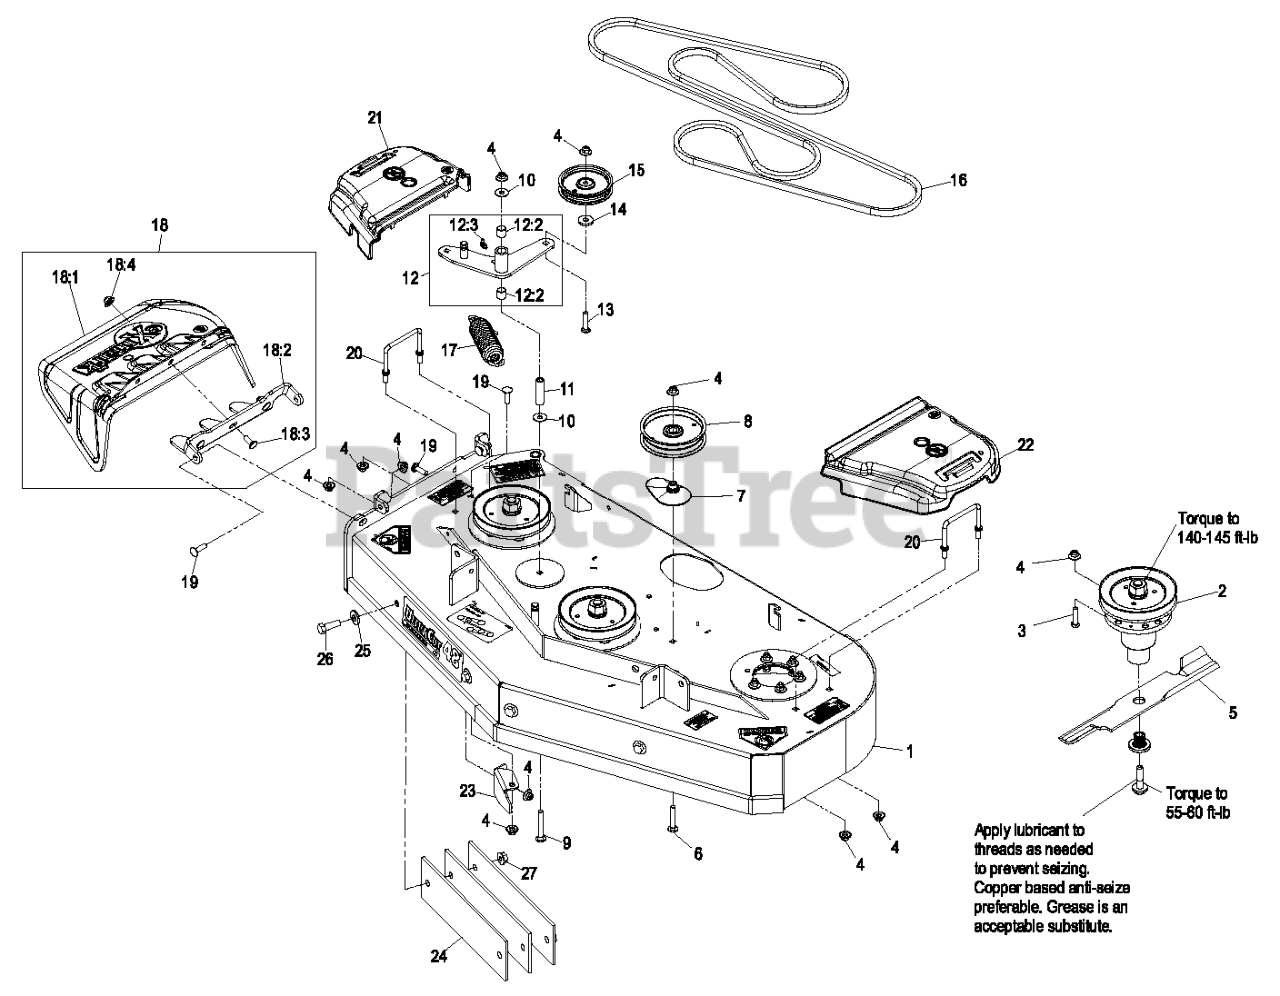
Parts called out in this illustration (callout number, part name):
1	DECK ASM, 484
2	KIT,CUTTER HOUSING 48
3	SCREW-HH
4	Nut-Nyloc 3/8-16 Flg
6	Bolt-Carriage 3/8-16 X 2 1/4
7	SPACER-PULLEY
8	PULLEY-IDLER
9	SCREW-CARR
11	BUSHING-PIVOT, IDLER
12	IDLER ASM
12:2	SLEEVE-BEARING
12:3	FITTING-GREASE, 90 DEG
13	SCREW-CARR SPECIAL
15	PULLEY-IDLER
16	V-BELT
18	ASM,DISCHARGE CHUTE
18:1	CHUTE,DISCHARGE
18:2	BRACKET,DISCHARGE CHUTE
18:3	SCREW-CARR
18:4	Nut-Nyloc 3/8-16 Flg
19	Bolt-Carriage 3/8-16 X 1 1/4
20	WIREFORM-COVER
21	COVER-BELT, RH
22	COVER-BELT, LH
23	BAFFLE,DISCHARGE
24	BAR,WEIGHT
25	WASHER-SPRING
26	SCREW-HH
27	NUT-HHF
